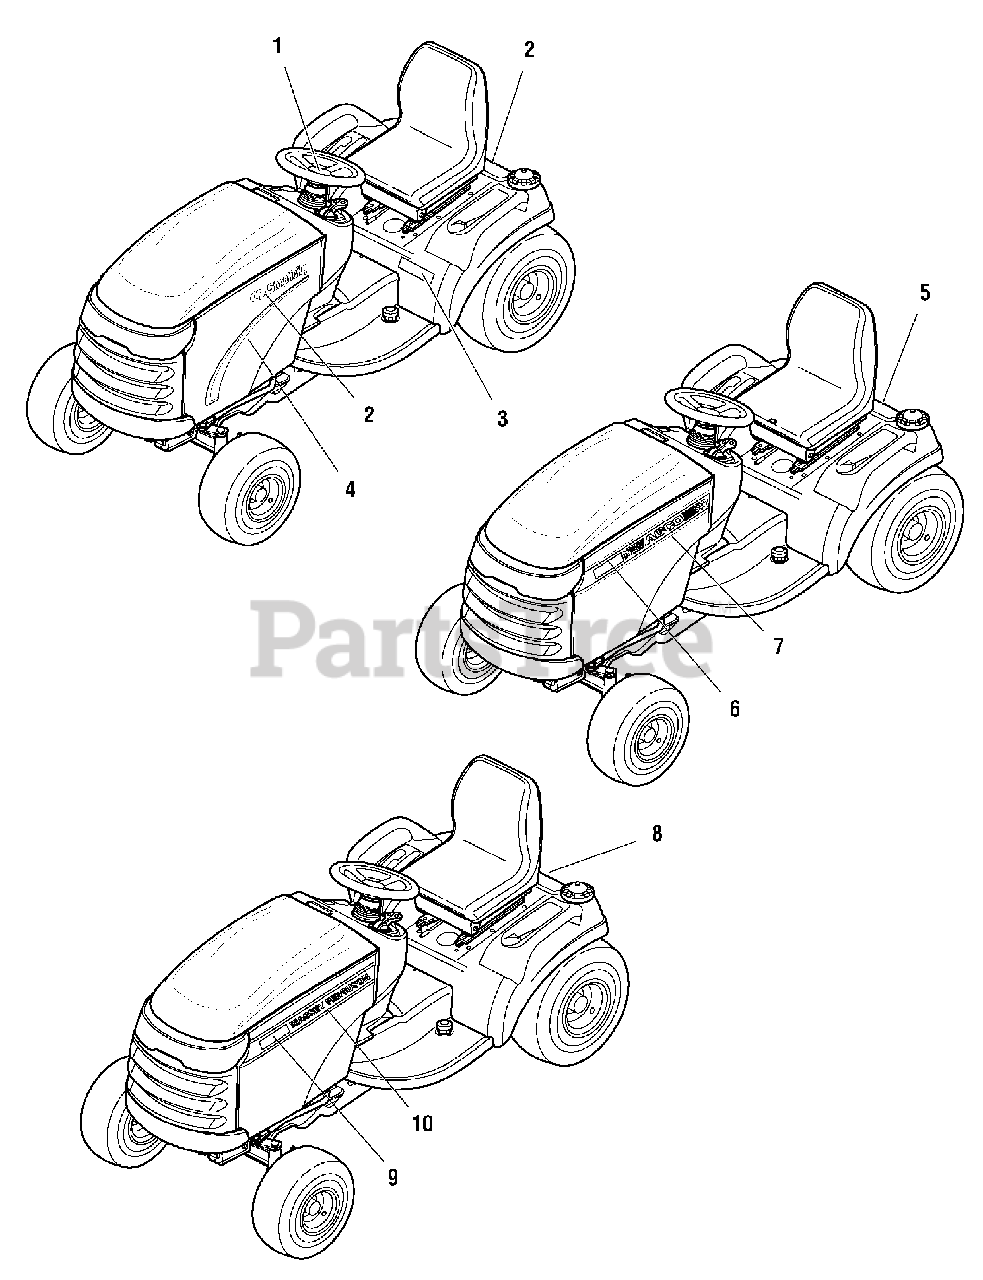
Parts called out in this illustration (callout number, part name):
1	DECAL, ICON Simplicity, Orange
2	DECAL, Simplicity, Silver & Blue w/Icon
3	DECAL, Broadmoor, Silver & Blue
4	DECAL, Hood Stripe, RH, Simplicity, Blue & Silver
4	DECAL, Hood Stripe, LH, Simplicity, Blue & Silver
5	DECAL, AGCO, Logo Black, Chrome, Orange
6	DECAL, 1620, White, AGCO
7	DECAL, Hood Stripe, RH, AGCO
7	DECAL, Hood Stripe, LH, AGCO
8	DECAL, Massey Ferguson Logo, 3 Triangles
9	DECAL, 2618, Black, Massey Ferguson
9	DECAL, 2618, Cool Grey, Massey Ferguson
9	DECAL, 2620, Black, Massey Ferguson
9	DECAL, 2620, Cool Grey, Massey Ferguson
9	DECAL, 2622, Cool Grey, Massey Ferguson
10	DECAL, Hood Stripe, LH, Massey Ferguson
10	DECAL, Hood Stripe, RH, Massey Ferguson
